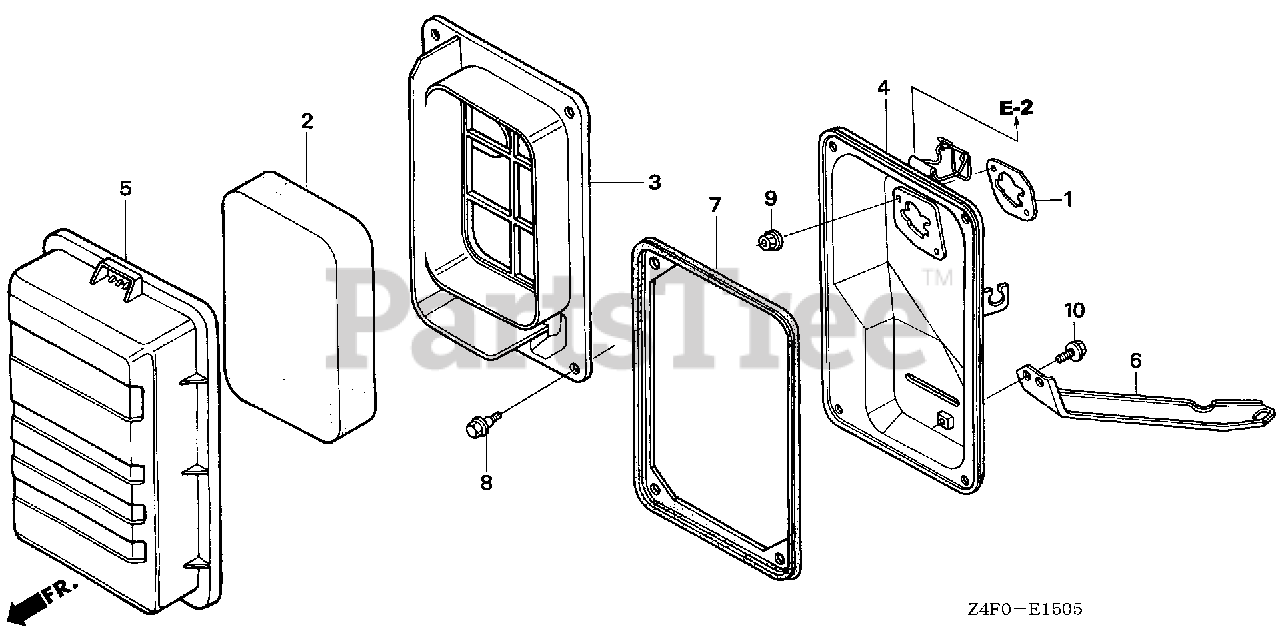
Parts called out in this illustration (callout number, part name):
1	GASKET, AIR CLEANER
2	ELEMENT, AIR CLEANER
3	SEPARATOR, AIR CLEANER
4	HOUSING, AIR CLEANER
5	COVER, AIR CLEANER
6	STAY, AIR CLEANER
7	SEAL, AIR CLEANER
8	BOLT, TURN SIGNAL SETTING
9	NUT, FLANGE (6MM)
10	BOLT, FLANGE (6X10)
